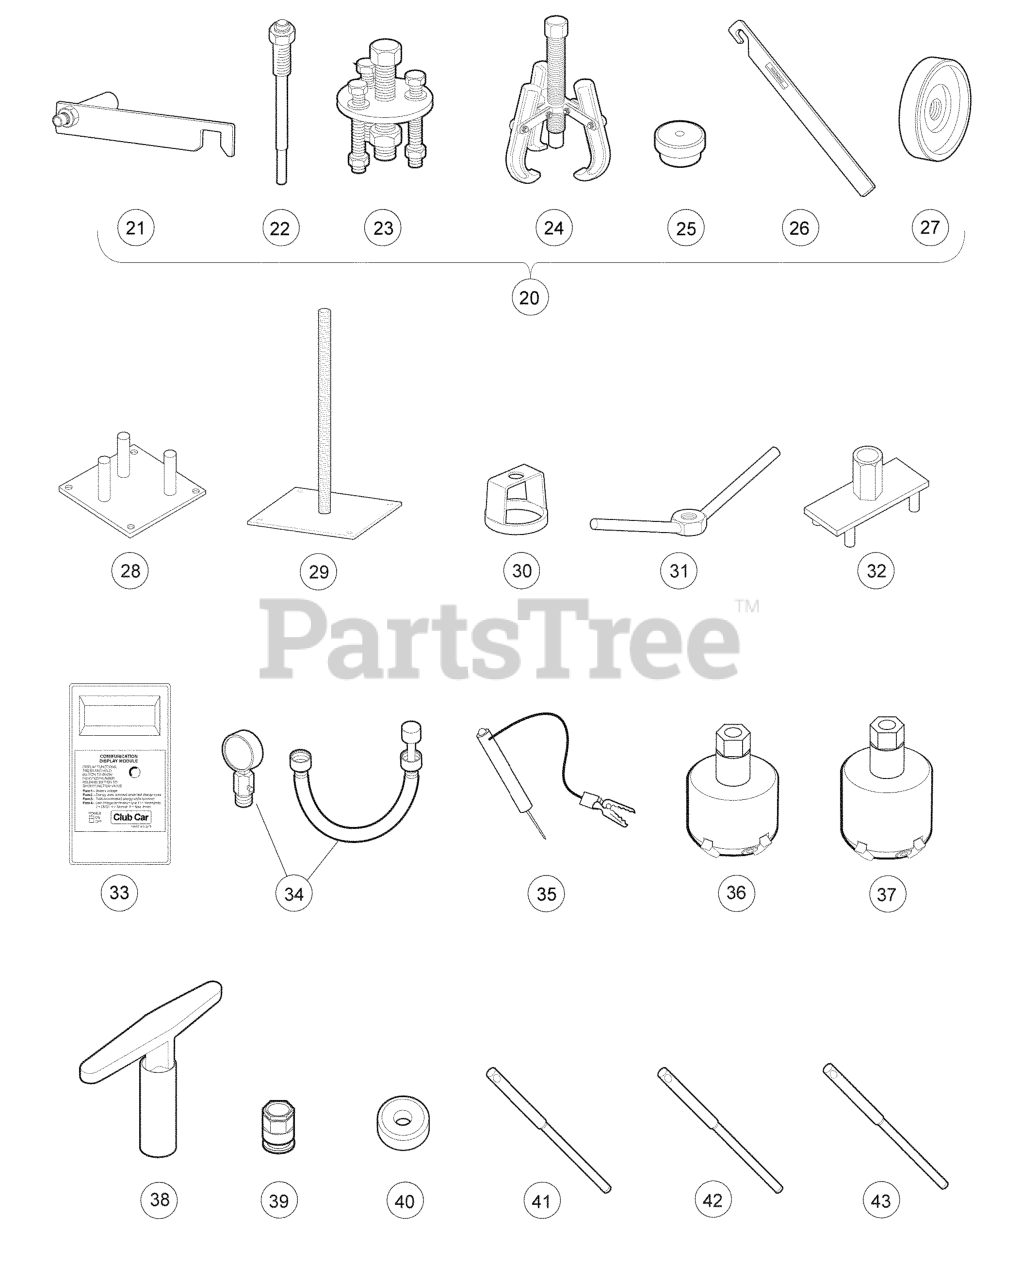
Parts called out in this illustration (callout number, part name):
1	TOOL, ACCEL. PEDAL ADJUSTMENT
2	GUIDE RING ADHESIVE 3 GRAMS
4	BATTERY DISCHARGE UNIT 36/48V
5	BATTERY TERMINAL PROTECT SPRAY
6	BATTERY THERMOMETER
7	BEAR & OIL SEAL REMOVER ASM
8	BEARING DRIVER SET
9	BEARING PULLER
10	BEARING PULLER WEDGE ATTACH.
11	BRAKE ADJUSMENT SOCKET TOOL
12	BRAKE CABLE RELEASE TOOL
13	Brake Pedal Adjustment Tool Kit
14	Brake Pedal Adjustment Tool
15	Brake Pedal Tension Tool
16	CALIBRATION & TEST MODULE
17	CAM INSTALLATION TOOL
18	CHARGER BEZEL TOOL
19	TOOL, REMOVAL, CLUTCH, GAS/DSL
20	C.C. CLUTCH TOOL KIT
21	TOOL, CLUTCH ALIGNMENT
22	TOOL, CLUTCH PULLER
23	CLUTCH DRIVE HUB PULLER
24	DRIVEN CLUTCH CAM PULLER
25	DRIVEN CLUTCH PULLER PLUG
26	DRIVE CLUTCH HOLDER TOOL ASM.
27	PRESS WELDMENT
28	TOOL-STATIONARY PRIMARY
29	TOOL-SPRING COMPRESSION BASE
30	TOOL-SPRING COMPRESSION COLAR
31	TOOL-SPRING COMPRESSION COLAR
32	TOOL-SPIDER PRIMARY
33	COMMUNICATION DISPLAY MODULE
34	COMPRESSION GUAGE AND ADAPTER
35	CONTINUITY TESTER
36	CUTTER, VALVE SEAT, #122
37	CUTTER, VALVE SEAT, #115
38	ADAPTER, T-WRENCH
39	ADAPTER, T-WRENCH
40	Cutter, Valve Seat, 60 Degree
41	PILOT, 6.6 MM
42	PILOT, 6.62 MM
43	PILOT, 6.65 MM
44	LUBRICANT 11OZ CAN SPRAY
45	FLYWHEEL PULLER KIT
46	GAUGE, CARB FLOAT LEVEL
48	INSERT TOOL, GOVERNOR SHAFT
49	ADJUSTER, HYDRAULIC BRAKE
50	HYDROMETER
51	INERNAL RETAINING RING PLIERS
52	KIT, IQDM, USER, SERIES II
53	KIT, IQDM, OEM, SERIES II
54	ADAPTER, 1307 CABLE
55	CABLE, IQDM, SERIES II
56	CABLE, IQDM
57	SEALANT
58	LUBRICANT, MOLY-TEFLON,4 OZ TU
59	TOUCH UP PAINT BEIGE
59	TOUCH UP PAINT, BLACK
59	TOUCH UP PAINT, BURGUNDY
59	TOUCH UP PAINT, CLASSIC BLUE
59	TOUCH UP PAINT, DARK GRAY
59	TOUCH UP PAINT, DARK GREEN
59	TOUCH UP PAINT, GRAY
59	TOUCH UP PAINT, RED
59	TOUCH UP PAINT, ROYAL BLUE
59	TOUCH UP PAINT, WHITE
60	PAINT, GRAY - SPRAY
61	PAINT PEN, UNDERBODY, BLACK
62	KIT, PISTON RING COMPRESSOR
63	PISTON RING PLIER
64	SPECIAL-USE PULLER SET
65	EXTERNAL SNAP RING PLIERS
66	INTERNAL SNAP RING PLIER 9O
67	SAFETY FIRST CARD
68	SEAL PULLER
69	WRENCH, SPANNER
70	Steering Column Bearing Press Tool
71	TOOL-STEERING RETAINING RING
72	PULLER, STEERING WHEEL
73	TACHOMETER GAS/DIESEL
74	TACHOMETER DIESEL ADAPTOR
75	TRANS-AXLE, AXLE SEAL TOOL
76	Transaxle Pinion Seal Tool
77	Transmission Tool Kit
82	VALVE CLEAR ADJ SCREW HOLDER
83	DRIVER, VALVE GUIDE, 6.6. MM
84	VALVE GUIDE REAMER
85	REAMER-VALVE GUIDE
86	VALVE SEAT CUTTER GUIDE
87	VALVE SEAT CUTTER "T" WRENCH
88	VALVE SEAT CUTTER 45 DEG 32 MM
89	CUTTER INTAKE VALVE ST 45/30
90	VALVE SPRING CMPR & ADAPTER
91	METER, WAVETEK VOLT-OHM
92	S/G TENSIONING TOOL
